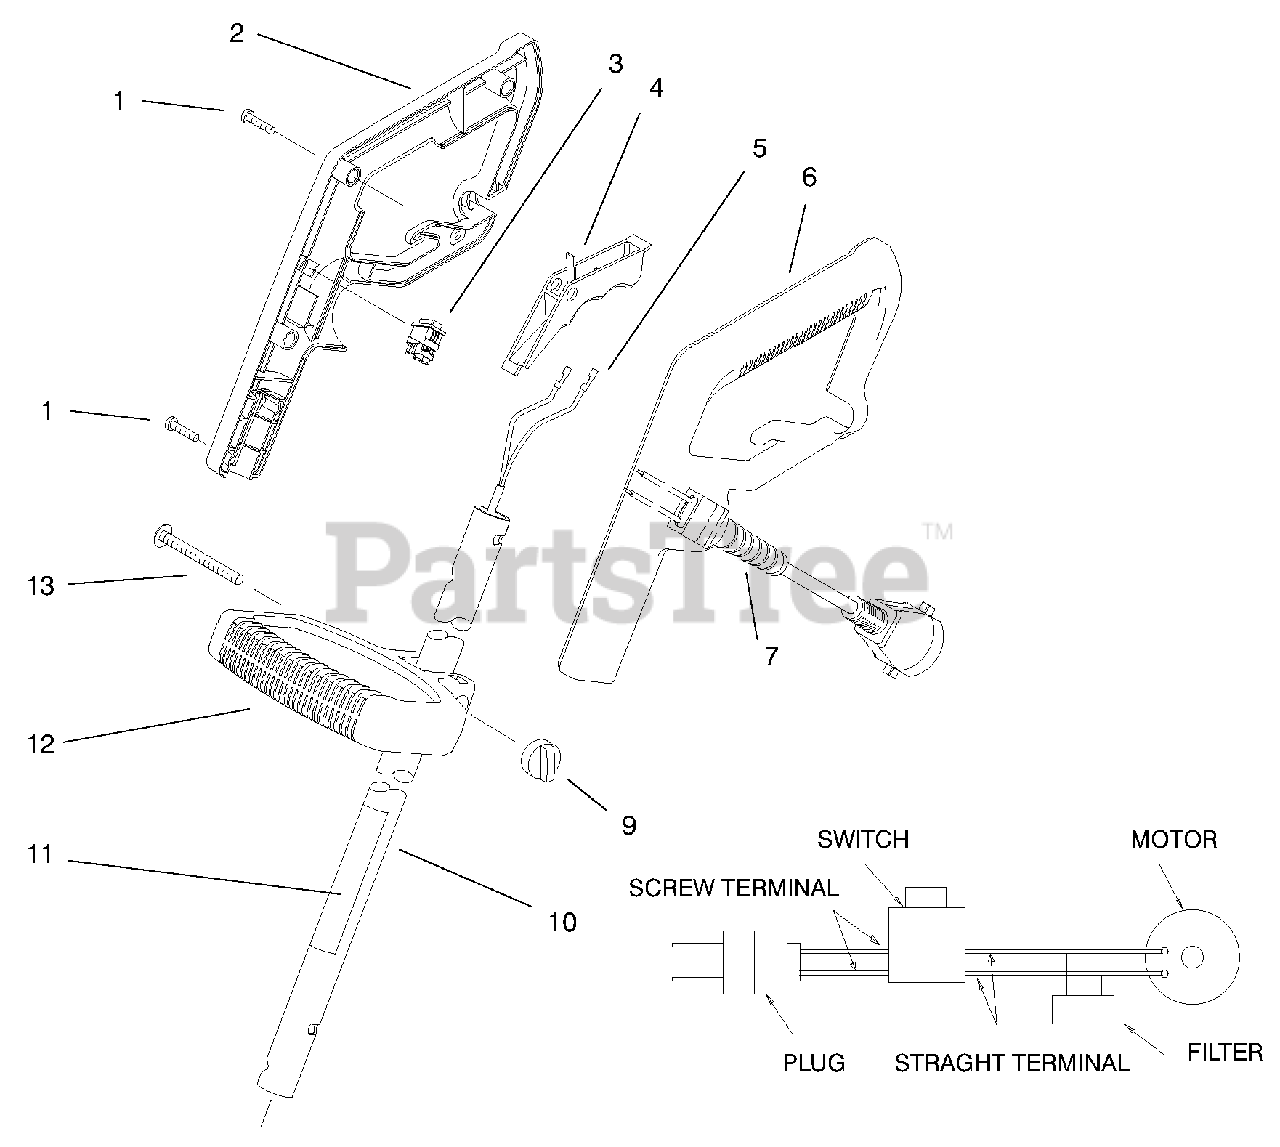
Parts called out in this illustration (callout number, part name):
1	Screw-Pan Hd Tapping
2	Grip-Hand R.H.
5	Harness-Wire
6	Grip-Hand L.H.
7	Cord-Power
10	Tube Assembly (Incl. Ref. #11)
11	Decal-Safety
12	Handle-Mid
13	Screw-Carriage
